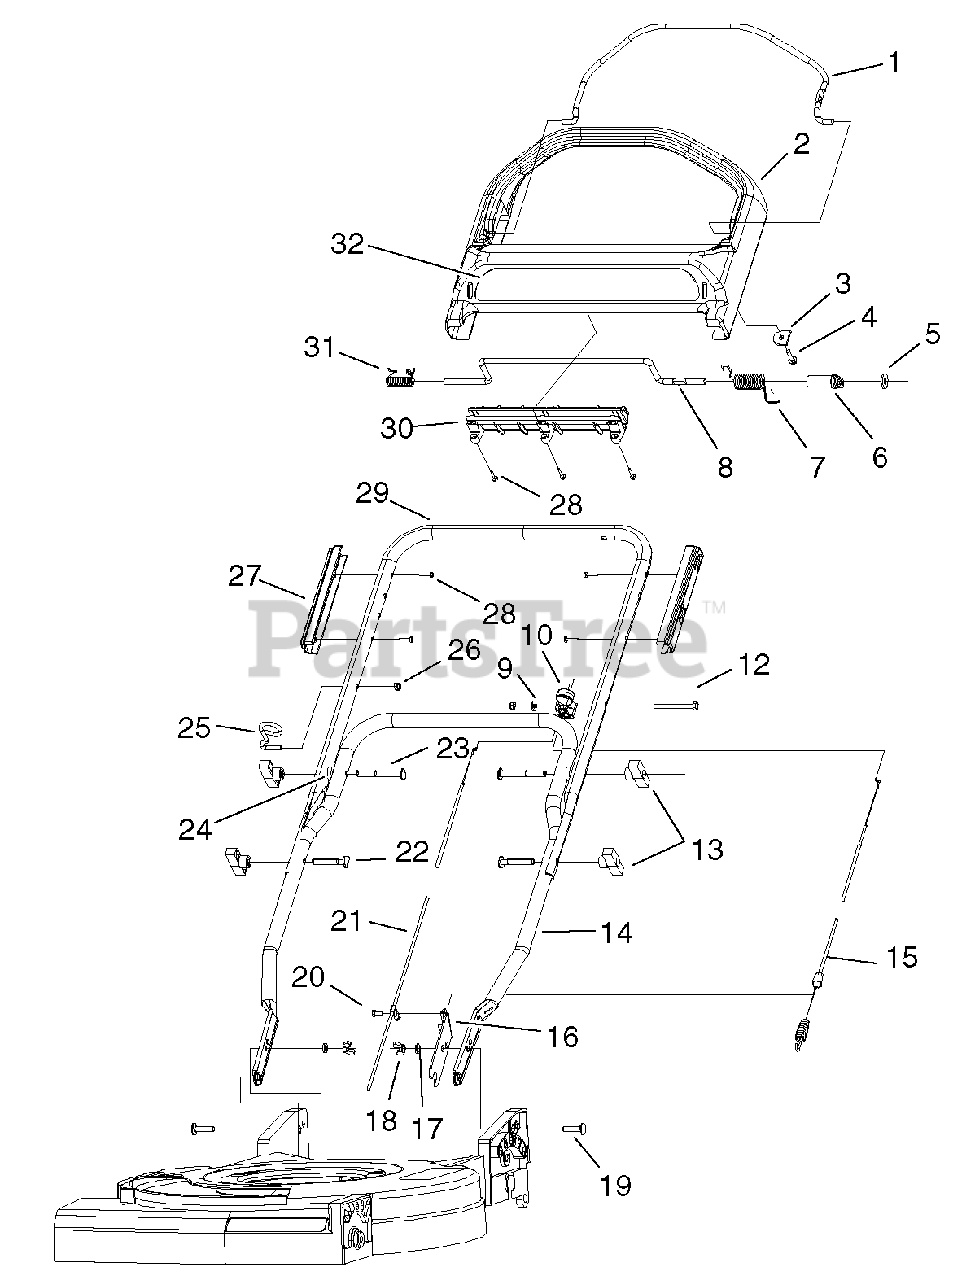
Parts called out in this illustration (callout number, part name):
1	Bail-Brake
2	Handle-Control
3	Retainer-Cable, Brake
4	Screw-HWH
5	Washer-Flat
6	Lever-Traction
7	Spring-Torsion
8	Bar-Control, Traction
9	Washer-Flat
10	Anchor-Cable
12	Screw-Handle
13	Knob-Handle
14	Handle-Lower
15	Cable-Traction
16	Bracket-Cable, Traction
17	Washer-Lock
19	Screw-CARR
20	Screw-Taptite
21	Cable-Brake, Flywheel
23	Screw-Handle
24	Spacer-Handle
25	Guide-Rope
26	Nut-Lock, NI
27	Guide-Handle, Control
28	Screw-PPH
29	Handle-Upper
30	Retainer-Control Rod, Traction
31	Spring-Torsion, RH
32	Decal-Handle
